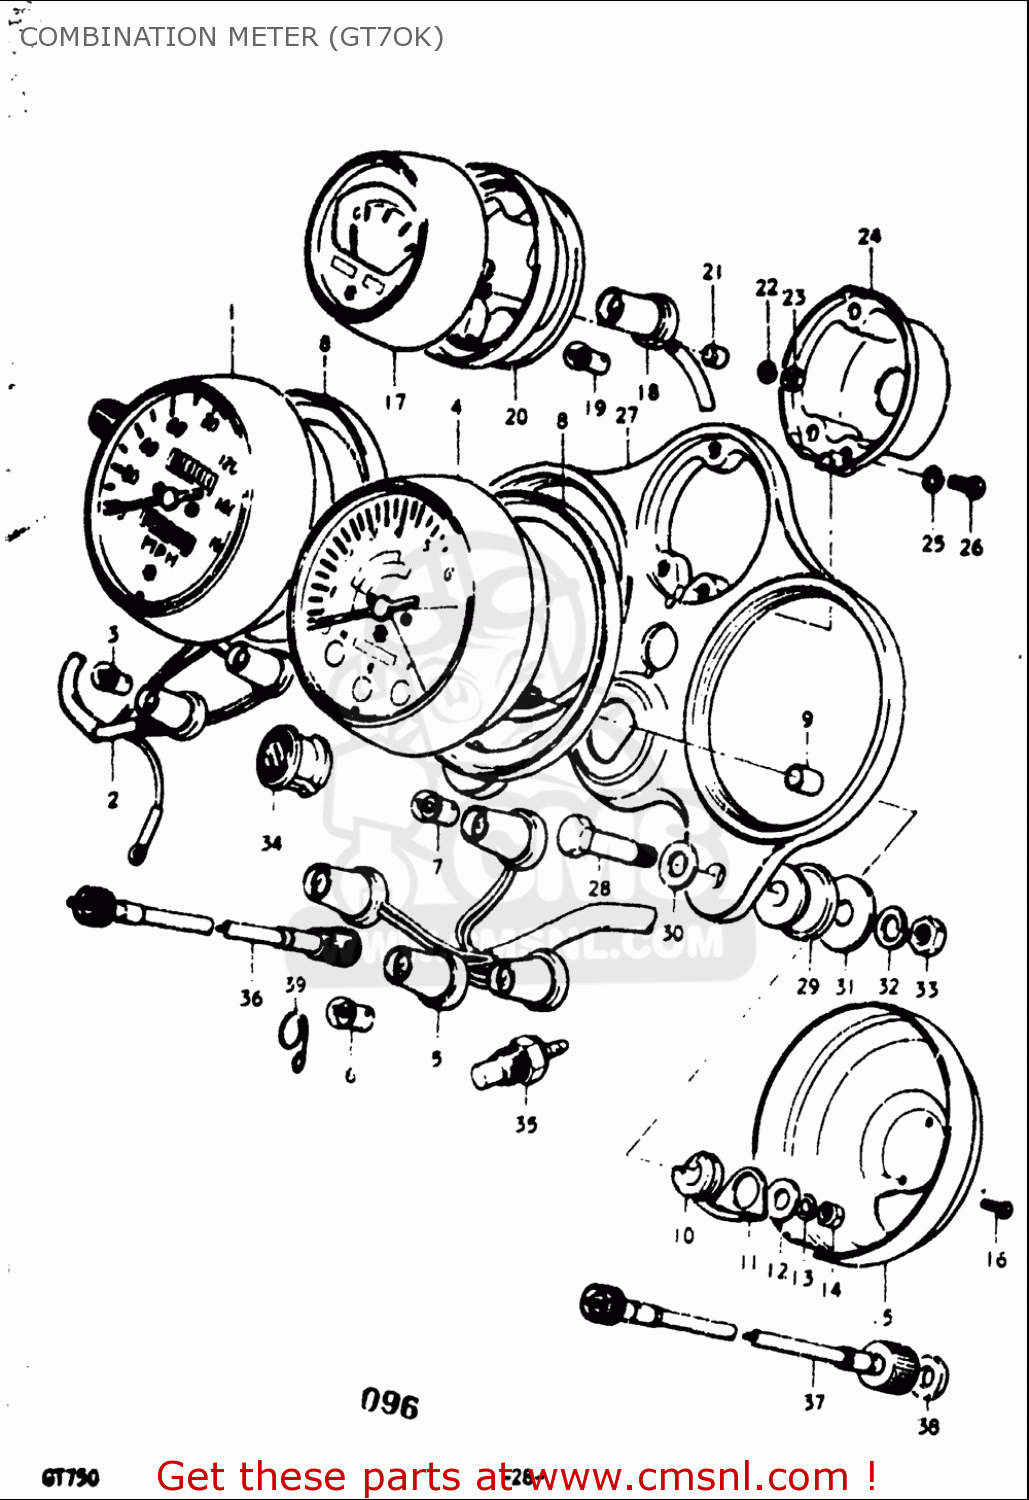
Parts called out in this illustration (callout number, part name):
3	BULB(12V3.4W,STANLEY,A72A)
6	BULB(12V3.4W,STANLEY,A72A)
7	BULB(12V1.7W,A71A)
8	CUSHION,SPEEDOMETER
9	SPACER,METER
12	WASHER(5.5X16X1.2)
13	WASHER,LOCK
14	NUT
15	PLATE,UNDER
16	SCREW
19	BULB(12V2W,STANLEY,A1272J)
22	WASHER,LOCK
23	NUT
25	WASHER,LOCK
26	SCREW
28	BOLT(8X39.2)
29	CUSHION,METER BRACKET
30	WASHER
32	WASHER,LOCK
33	NUT
34	CAP,SPEED WARNER LAMP HOLE
35	GAUGE ASSY,WATER TEMP
36	CABLE ASSY,SPEEDOMETER
37	CABLE ASSY,TACHOMETER
38	SEAL,OIL SPEEDOMETER CABLE
39	CLIP
